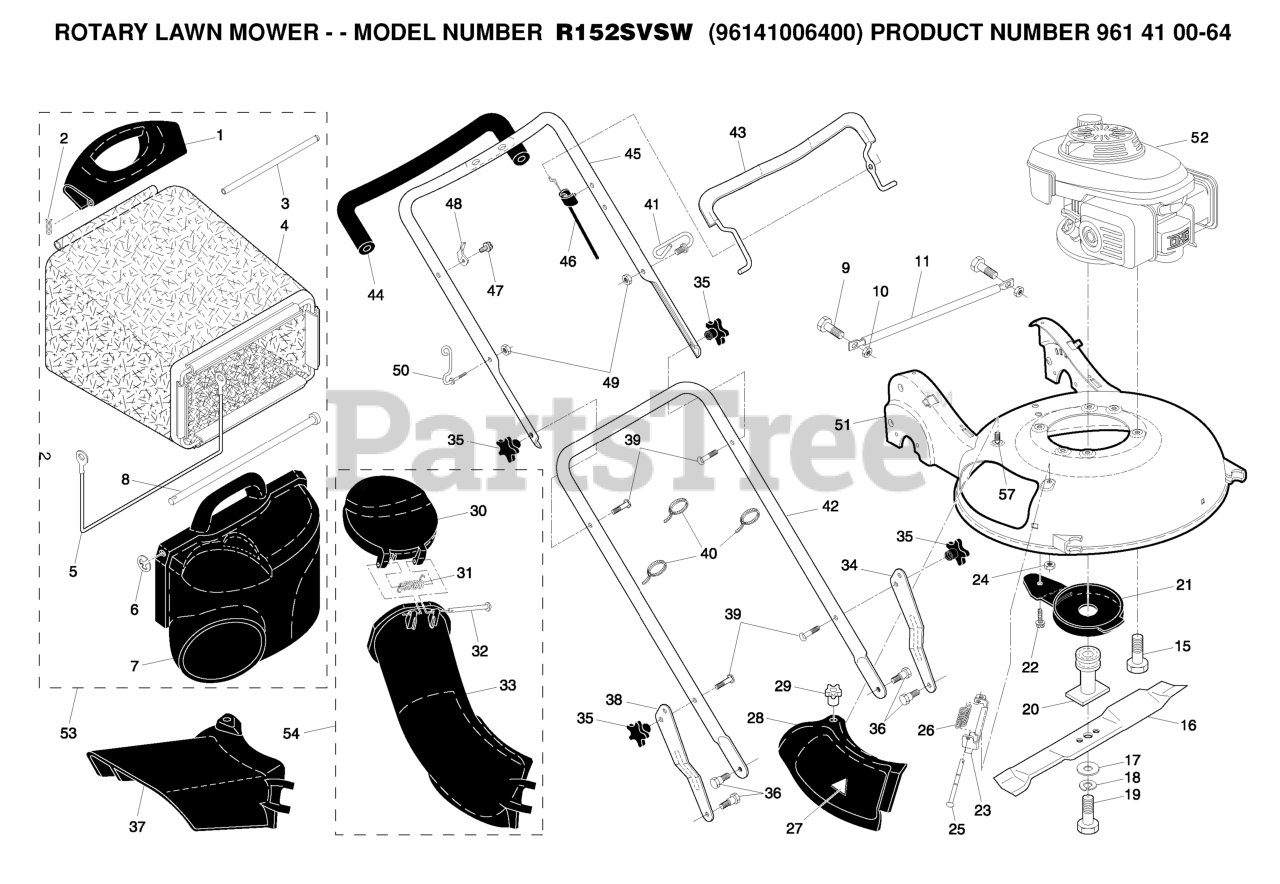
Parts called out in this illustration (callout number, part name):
1	HANDLE.GRASSBAG.REAR.H-GRAY
2	COTTER PIN (3 2)(2 2MC)
3	ROD.REAR.HANDLE.YELLOW
5	FRAME, GRASSBAG
7	DOOR, GRASSBAG
8	ROD, PIVOT
10	LOCKNUT.NYLOC.1/4-20
11	TUBE, REAR SKIRT
15	BOLT 3/8-16X1-1/8
16	BLADE.21.PUSH
17	WASHER,HARDEN
18	LOCKWASHER
19	BOLT.HD.HEAD.3/8-24X2.50 (2 2)
20	ADAPTER.BLADE
21	DEBRIS SHEILD
22	SCREW 1/4X20
24	LOCK NUT
25	ROD.HINGE.1/4"3.82"
26	SPRING.MULCH.DOOR
27	DECAL.INTERNATIONL.CUTFINGER
28	MULCHER DOOR
29	KNOB.MULCH.DOOR
30	CHUTE.DOOR.21.HV.H-GRAY
32	ROD.HINGE.1/4"3.82"
33	DISCHARGE CHUTE PLASTIC
34	ADJUSTMENT BRACKET, LOWER LH
35	KNOB.HANDLE.STAR.HUSQ.GRAY
36	SCREW.5/16X.680.TRIM.H
37	GUARD.CLIP.ON.21.HV.GRAY
38	BRACKET.ADJ.LOWER.HDL.RT.GREY
39	BOLT, HANDLE 5/16-18X1.75
40	TIE GUIDE
42	HANDLE.LOWER.GREY
43	BAIL CONTROL
44	GRIP.HANDLE.FOAM.WIDE.(1 SIDE)
45	HANDLE.ASM.UPPER.W/GRIP
46	CABLE.MZR.50.SNAP-IN
48	BRACKET
49	NUT
50	GUIDE.ROPE.WALK.MOWER
53	Grassbag Assembly, Complete
54	CHUTE.LOWER.ASM.WALK.MOWER
57	STUD.SHOULDER.T45.BZP
